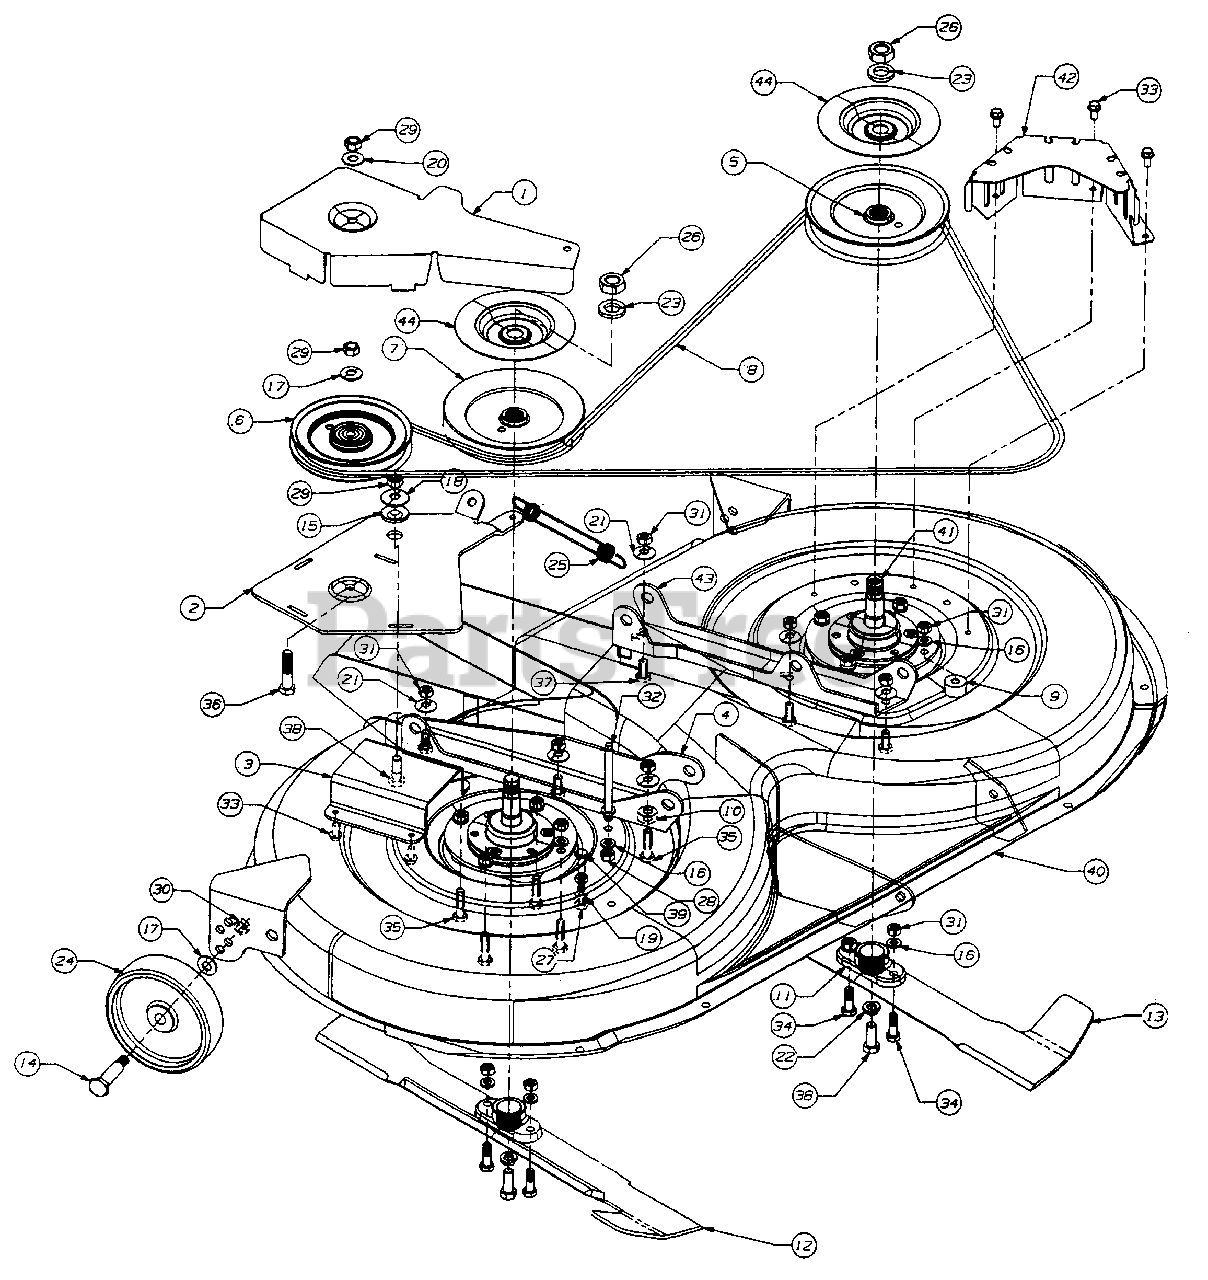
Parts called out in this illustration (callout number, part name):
6	Idler Pulley
7	Deck Pulley - R.H.
8	"V"-Belt
9	Spacer .33" I.D. x .88" O.D.
10	Spacer .315" I.D. x .375" Lg.
11	Blade Adapter
12	Blade - R.H.
13	Blade - L.H.
14	Shld. Bolt. 498" Dia. x 1.53" Lg.
15	Shld. Spacer. 625" I.D.
16	L-Wash. 5/16" I.D.
17	Bell-Wash. .38" I.D. x .88" O.D.
18	Bell-Wash. .39" I.D. x 1.13" O.D.
19	L-Wash. 1/4" I.D.
20	Fl-Wash. 3/8" I.D. x 7/8" O.D.
21	Bell-Wash. .34" I.D. x .87" O.D.
22	L-Wash. 3/8" I.D. (Hd.)
23	L-Wash. 5/8" I.D.
24	Deck Wheel
25	Ext. Spring 6.12" Lg.
26	Hex Jam Nut 5/8-18 Thd.
27	Hex Nut 1/4-20 Thd.
28	Hex Nut 5/16-18 Thd.
29	Hex Nut 3/8-24 Thd.
30	Hex Jam Nut 3/8-16 Thd.
31	Hex Nut 5/16-24 Thd.
32	Belt Guard Stud
33	Hex Wash. Hd. Tap Scr. 1/4-20 x .5" Lg.
34	Hex Bolt 5/16-24 x 1" Lg. (Gr. 5)
35	Hex Bolt 5/16-24 x 1.25" Lg. (Gr. 5)
36	Hex Bolt 3/8-24 x 1.75" Lg.
37	Hex Bolt 5/16-24 x .75" Lg. (Gr. 5)
38	Hex Bolt 3/8-24 x 1" Lg.
39	Hex Bolt 1/4-20 x 1.75" Lg.
